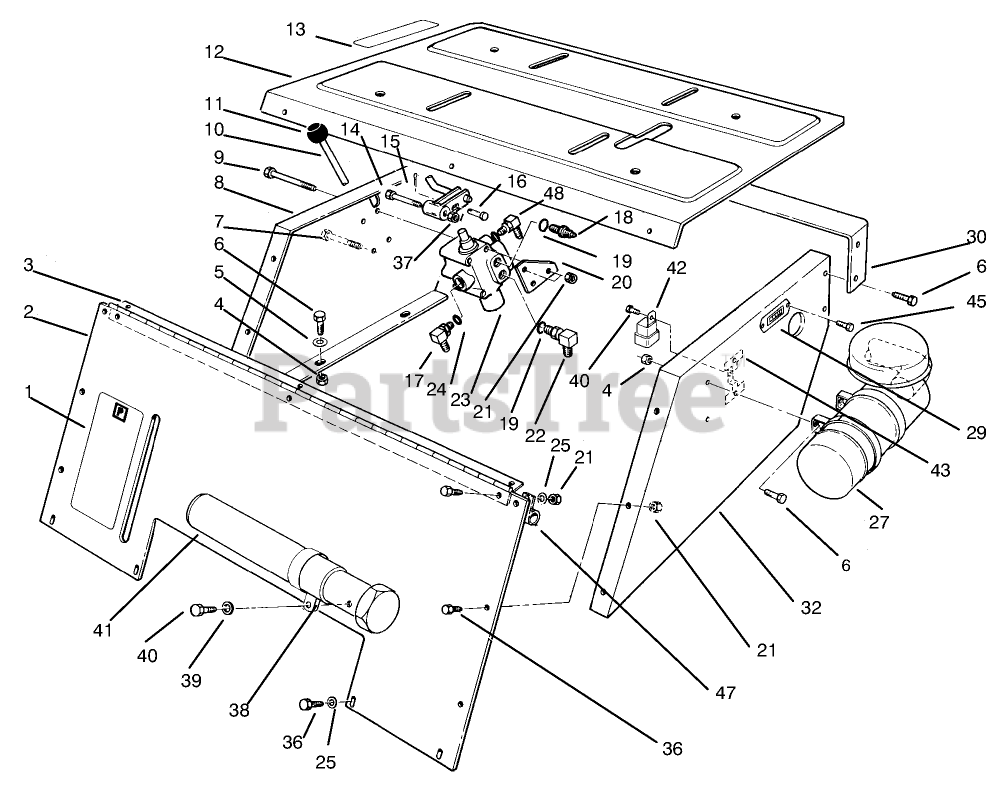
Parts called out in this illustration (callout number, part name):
1	PARK BRAKE DECAL
2	Support-Seat, Front
3	Hinge-Seat
4	NUT-LOCK, NI
5	WASHER-PLAIN
6	SCREW-HH
7	SCREW-HH
8	Support-Seat RH.
9	SCREW-HH
10	Lever-Valve
12	Plate-Seat
13	LIFT CONTROL DECAL
14	BOLT-WHEEL
15	PIN-COTTER
16	PIN-CLEVIS
17	FITTING-HYD, 90 DEG
18	FITTING-STRAIGHT
19	O-RING
20	LEVER BRACKET
21	NUT-LOCK, NI
22	FITTING-ELBOW, 90
23	VALVE ASM
24	O-RING
25	WASHER-FLAT
27	AIR CLEANER KIT
29	HOURMETER
30	Support-Hood
32	Support-Seat L.H.
36	SCREW-HH
37	NUT-LOCK, NI
38	CLAMP-R
39	WASHER-FLAT
40	SCREW-HWH
41	TUBE-MANUAL
42	RELAY
43	Bracket
45	SCREW-HWH
47	CLAMP
48	FITTING-ELBOW-90 DEG
